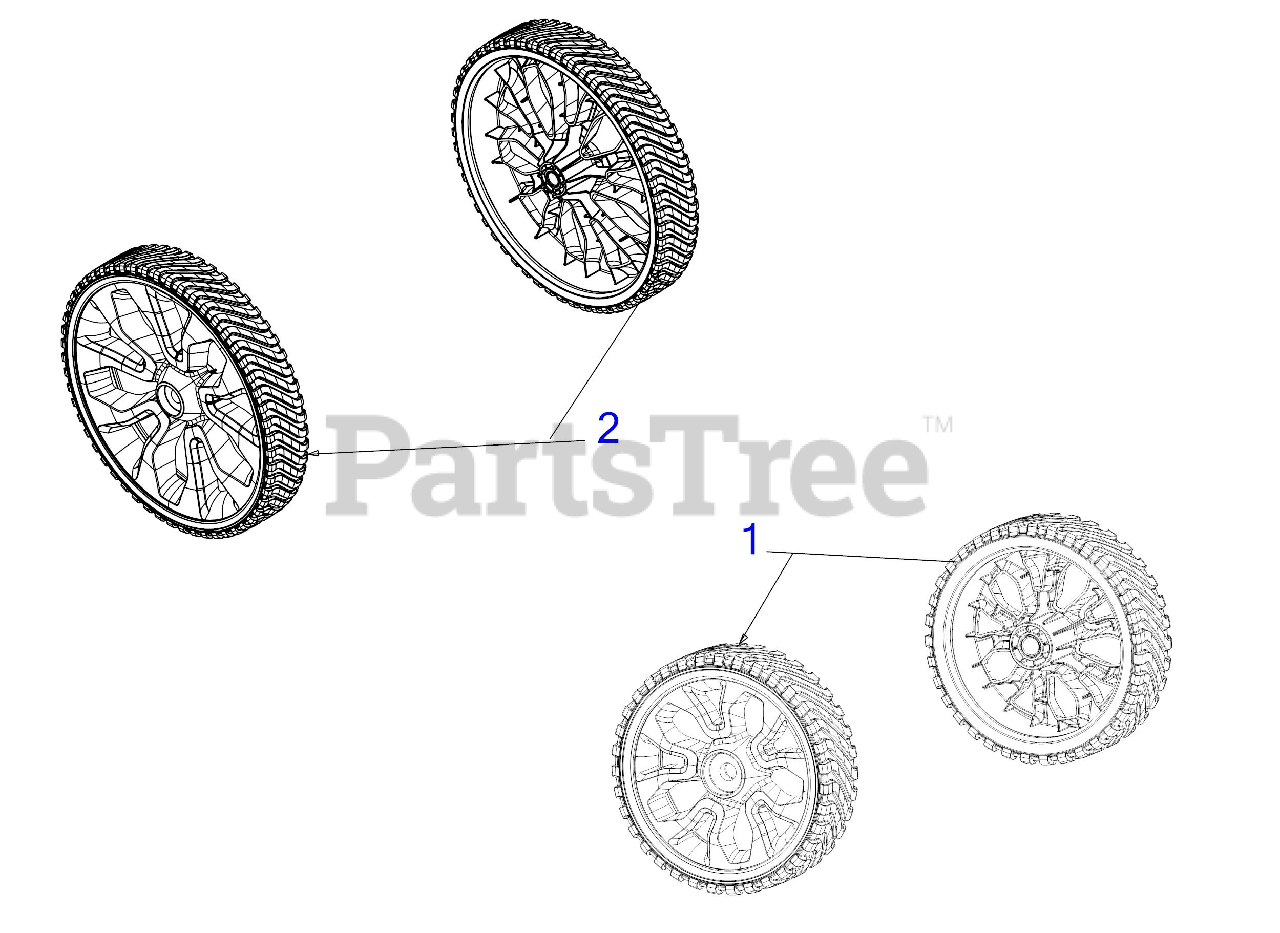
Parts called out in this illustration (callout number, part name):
1	WHEEL ASSEMBLY 7 X 2 GRAY
1	Genuine Factory Parts WHEEL ASSEMBLY (7x2x1/2)(GRAY)
2	WHEEL ASSEMBLY 11 X 2 GRAY
2	Genuine Factory Parts WHEEL ASSEMBLY (11x2x1/2)(GRAY)
2	Troy-Bilt WHEEL ASSEMBLY (11x2x1/2) (GREY)
